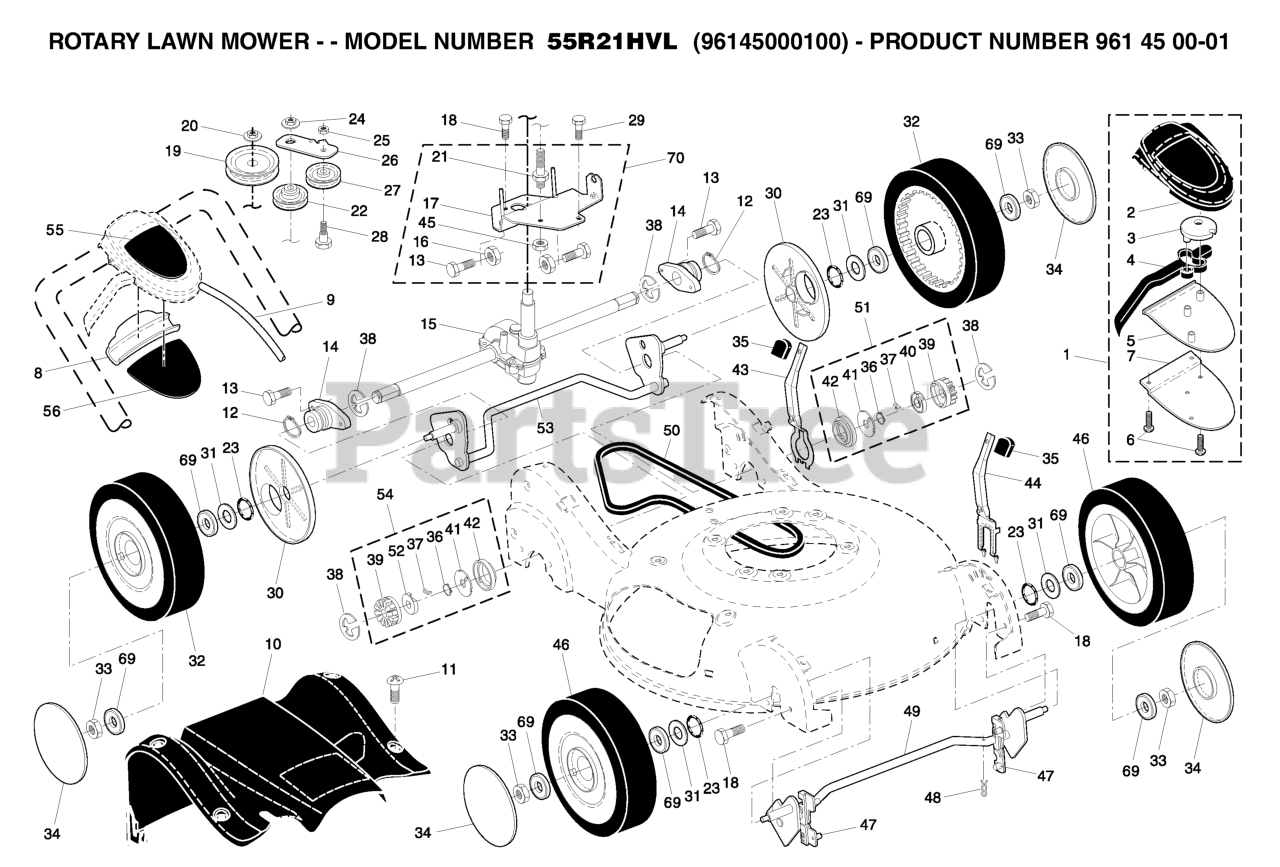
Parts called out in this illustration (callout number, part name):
1	EZ WALK CONTROL
2	COVER, DRIVE CONTROL, TOP
3	PULLEY.CAM.DRIVE.CONTROL.HV
4	LEVER
5	COVER, DRIVE CONTROL BOTTOM
6	SCREW, PHILLIPS HEAD 10 X 5/8
7	BRACKET, DRIVE CONTROL
8	EZ WALK SNAP COVER PLATE
9	CABLE, DRIVE CONTROL
10	COVER ASM. DRIVE
11	SCREW
12	RETAINING RING (2 2)(3 2)
13	RP SCREW
14	BEARING.SUPPORT.ASSEM
15	TRANSMISSION.21.HI-VAC.EZ
16	NUT
17	BRACKET TRANSMISSION
19	RP PULLEY DRIVE
20	FLANGED LOCKNUT 3/8-16 ZINC
21	BOLT, IDLER
22	PULLEY ASSY
23	O-RING
24	NUT
25	NUT.CENTERLOCK.5/16-
26	BRACKET
27	IDLER PULLEY
28	SHOULDER BOLT
29	SCREW 14-20 X 5/8
30	DUST COVER, WHEEL
31	WASHER.FLAT.1/2
32	WHEEL.9X2.25.LP.TIGER.BLACK
33	HEX FLANGE LOCKNT
34	RB HUBCAP.3-SPOKE.SILVER
35	KNOB.SELECTOR.SPRG.H-GRY (2 2)
36	SPRING, TORSION
37	PAWL.DRIVE.21.EZ-WALK
38	E-RING 7/16 RE
39	GEAR, PINION
40	RETAINER.DRIVE.21.EZ-WALK.LT
41	DISC.DRIVE.21.EZ-WALK
42	SEAL.PINION
43	LEVER, SELECTOR, HEIGHT, REAR
44	LEVER, SELECTOR, HEIGHT, FRONT
45	JAM NUT TI
46	WHEEL.9X2.25.LP.TIGER.BLK
47	BUSHING.FRONT.TORQUE.SHAFT
48	SPRING RETAINER
49	TORQUE SHAFT ASSY
50	BELT.DRIVE.EZ.WALK.HI-VAC
51	PINION ASSY, LH
52	RETAINER, DRIVE, RH
53	REAR AXLE ASSY.
54	PINION ASSY, RH
55	DECAL.DRIVE.CONTROL.HV
69	BEARING.8".WHEEL
